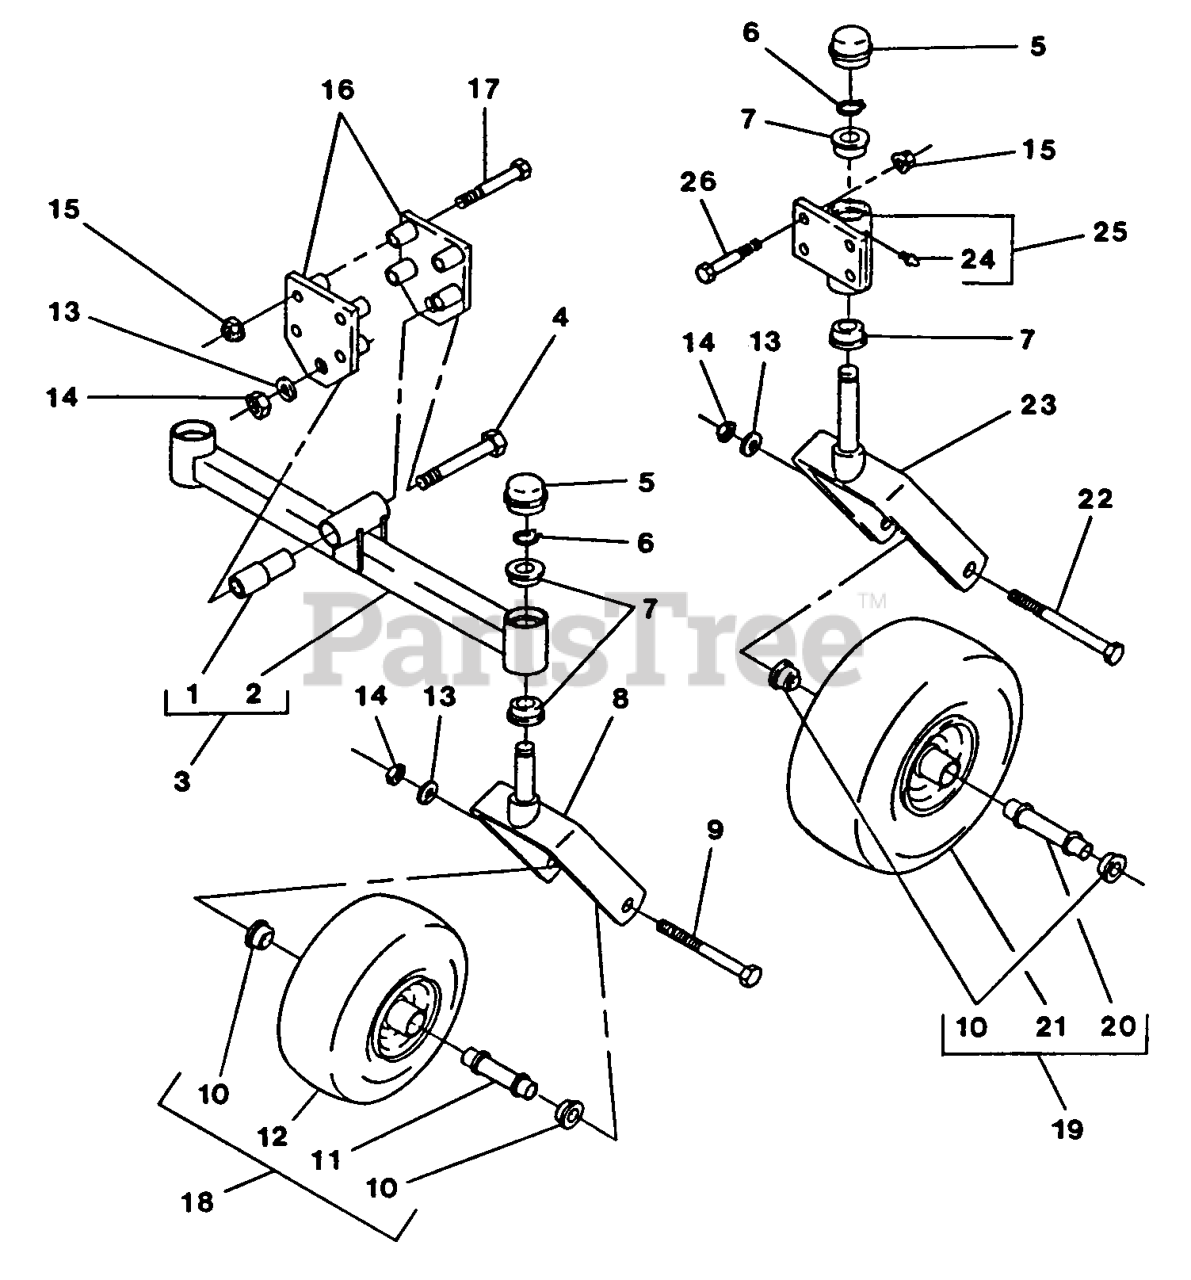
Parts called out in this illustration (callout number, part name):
5	CAP,GREASE
7	BEARING,FLANGED
11	WLD,WHEEL SPACER
18	ASM,CASTER WHEEL
20	SPACER WLDMT,WHEEL
23	WLD,CASTER FORK
25	WLD,CASTER MOUNT
